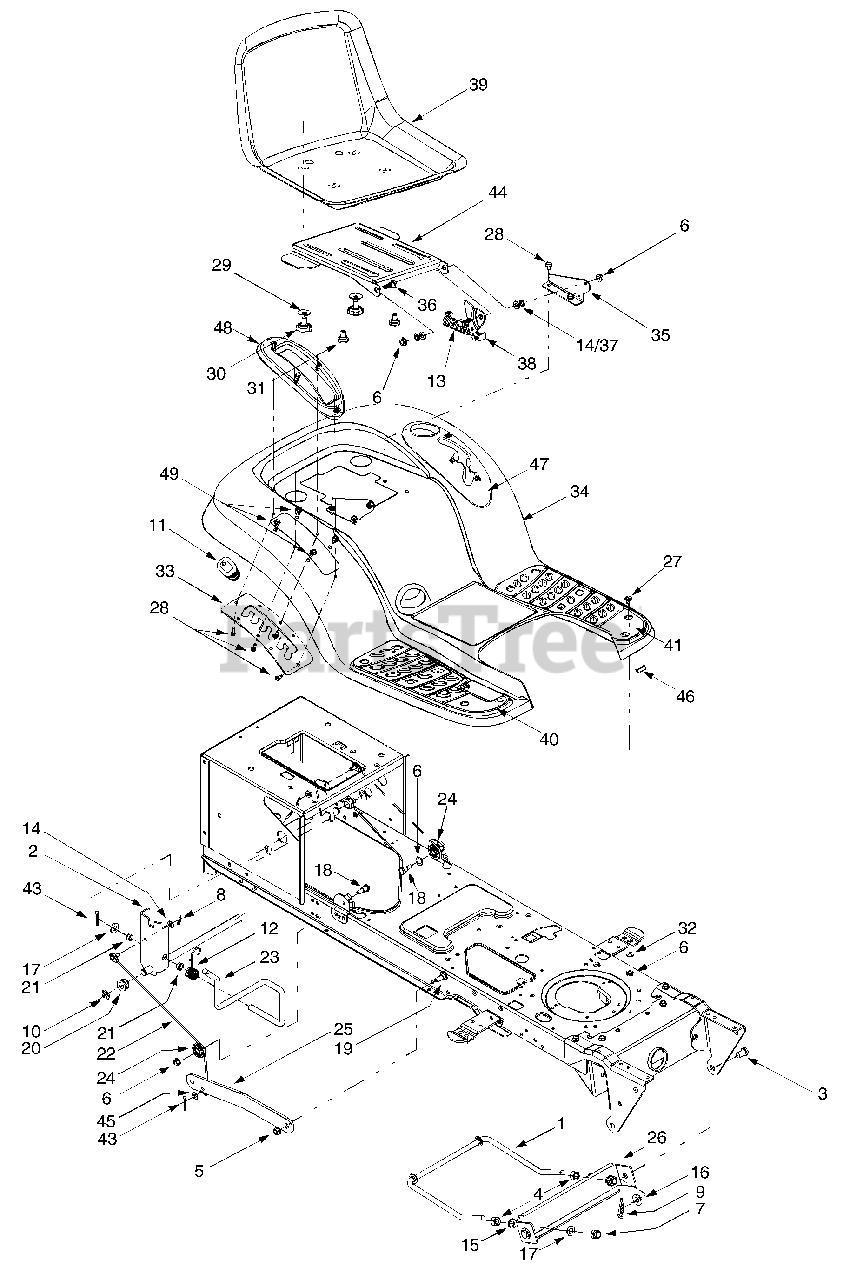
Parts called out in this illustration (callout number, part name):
1	Deck Stabilizer Rod
3	Clevis Pin, .5 x .78
4	Hex Nut, 1/2-13
5	Flange Lock Nut, 3/8-16
6	Flange Lock Nut, 5/16-18
7	Hex Nut, 1/2-13
8	Internal Cotter Pin
9	Internal Cotter Pin
11	Handle Grip
12	Torsion Spring
13	Extension Spring, .84 x 4.6
14	Flat Washer, 5/16
15	Lock Washer, 1/2
16	Flat Washer, .531 x 1.062 x .134
17	Flat Washer, .51 x 1.12 x .06
18	Hex Cap Screw, 5/16-18 x .62
19	Shoulder Screw, 3/8-16
20	Hex Flange Bearing
21	Snap Flange Bearing
22	Lift Cable, 16.16 (LTX-1842)
23	Lift Handle
24	Roller Pulley
27	Carriage Bolt, 5/16 x .62
28	Self-tapping Screw, 5/16-18 x .625
29	Bell Washer, .390 x 1.13 x .062
30	Knob, 3/8-16
31	Shoulder Screw
32	Flat Washer, .349 x 1.0 x .063
36	Shoulder Screw
37	Speed Clip
38	Seat Lift Bracket
39	Medium Back Seat, Black
40	RH Foot Pad, Rubber
41	LH Foot Pad, Rubber
43	Cotter Pin
45	Flat Washer, .344 x .62
46	Trim Strip
47	Lift Lever Cover
48	Shift Lever Cover w/ Cup Holder
49	Self-tapping Screw, 1/4-15 x .75
